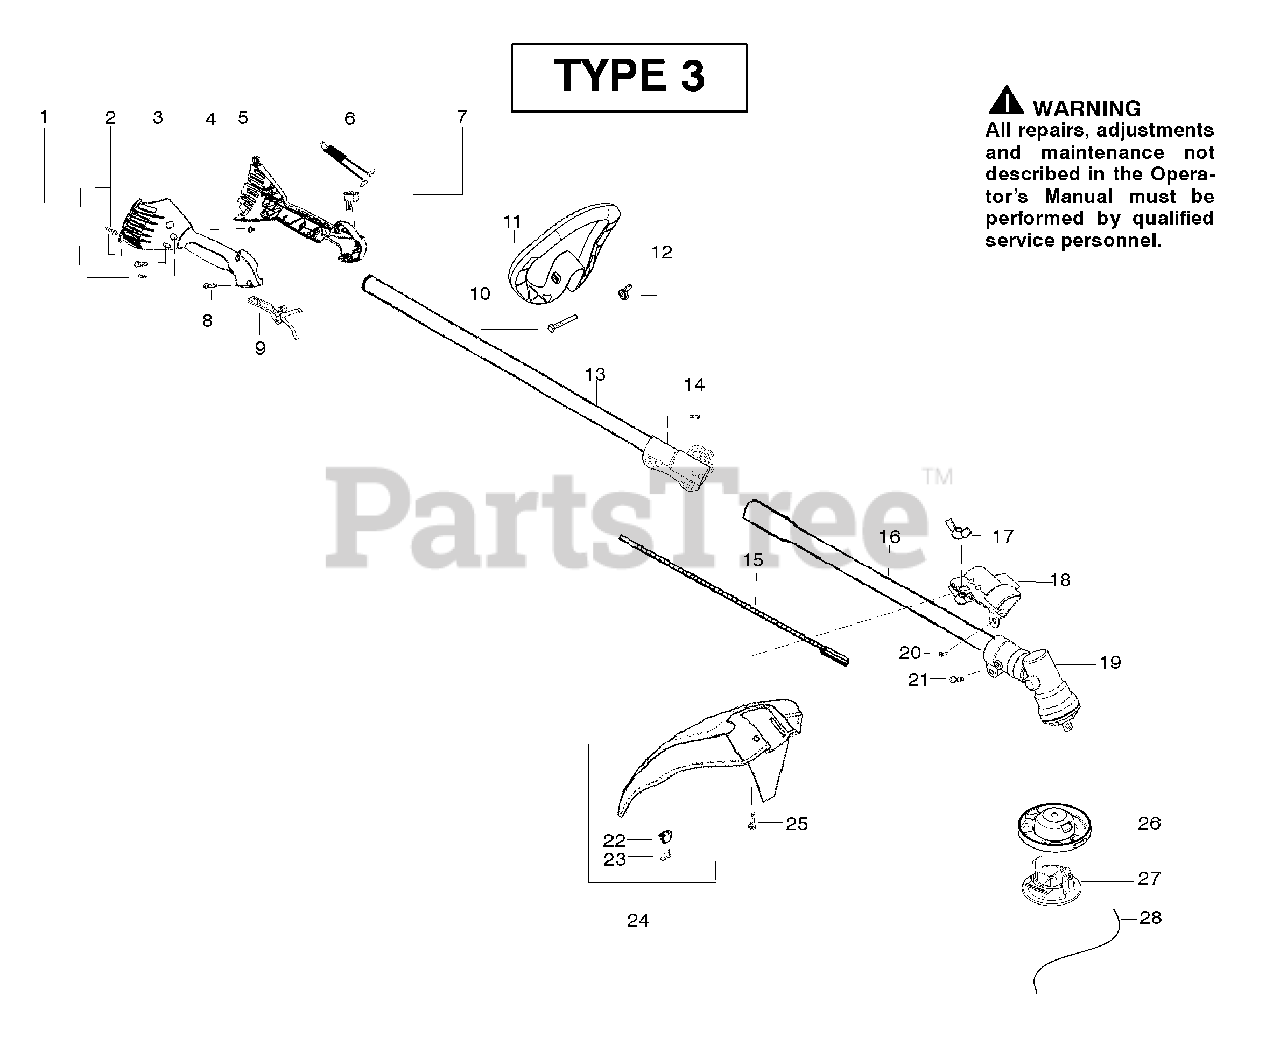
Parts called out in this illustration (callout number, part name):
1	Screw-alignment
3	Hsg.-Throttle right
4	Screw-Cable Retention
5	Hsg.-Left throttle
6	Assy-Wire
7	Kit-Switch
9	Lever-Throttle
11	Assy-Handle
12	Wingnut
13	Kit-Upper Shaft
15	Shaft-Flex
16	Kit-Lower Shaft
17	Wingnut
18	Bracket-Shield
22	Limiter-Line
24	Kit-Shield Assy.
26	Head-Fixed Line
27	Cap-Fixed Line
28	Accy-Line
